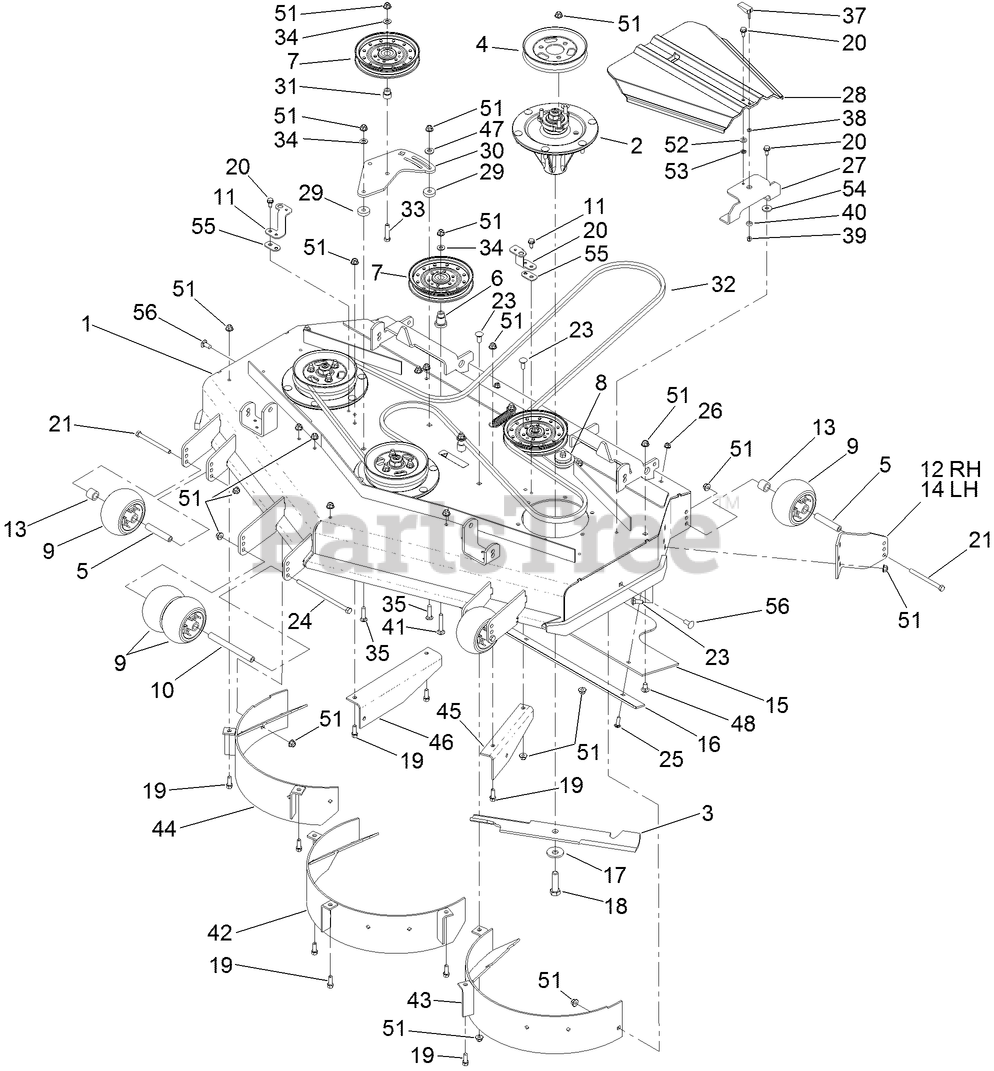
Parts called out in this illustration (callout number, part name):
1	DECK DECAL ASM
2	SPINDLE ASM
3	BLADE-18IN, HI FLOW
4	Pulley
5	TUBE-SPANNER
6	MOUNT-PULLEY
7	IDLER-PULLEY, FLAT
8	SPRING IDLER ASM
9	ROLLER-SCALP, ANTI
10	SPACER-WHEEL
11	BRACKET-COVER, TALL
12	MOUNT-ANTI SCALP, RH
13	TUBE-SPACER
14	MOUNT-ANTI SCALP, LH
15	DEFLECTOR-RUBBER
16	SKID-SKIRT
17	Washer-Blade Bolt, Heavy
18	SCREW-BLADE
19	SCREW-HWH
20	SCREW-HWHTF
21	SCREW-HH
23	BOLT-CARR
24	SCREW-HH
25	SCREW-CARR
26	NUT-HF, NI
27	BRACKET-BELT COVER
28	COVER-BELT
29	Spacer
30	PLATE-IDLER
31	BUSHING-IDLER
32	BELT-V
33	SCREW-HH
34	WASHER-FLAT
35	SCREW-CARR
37	HANDLE-LATCH, SWELL
38	WASHER
39	NUT-LOCK, HH
40	BUSHING-LATCH, SWELL
41	SCREW-CARR
42	BAFFLE-CENTER
43	BAFFLE-LH
44	BAFFLE-RH
45	BAFFLE-TRAILING
46	BAFFLE-TRAILING
47	WASHER-BELLEVILLE
48	SCREW-CARR
51	NUT-HF, NI
52	WASHER-THRUST
53	NUT-PUSH
54	WASHER
55	SPACER-BELT COVER
56	SCREW-CARR
